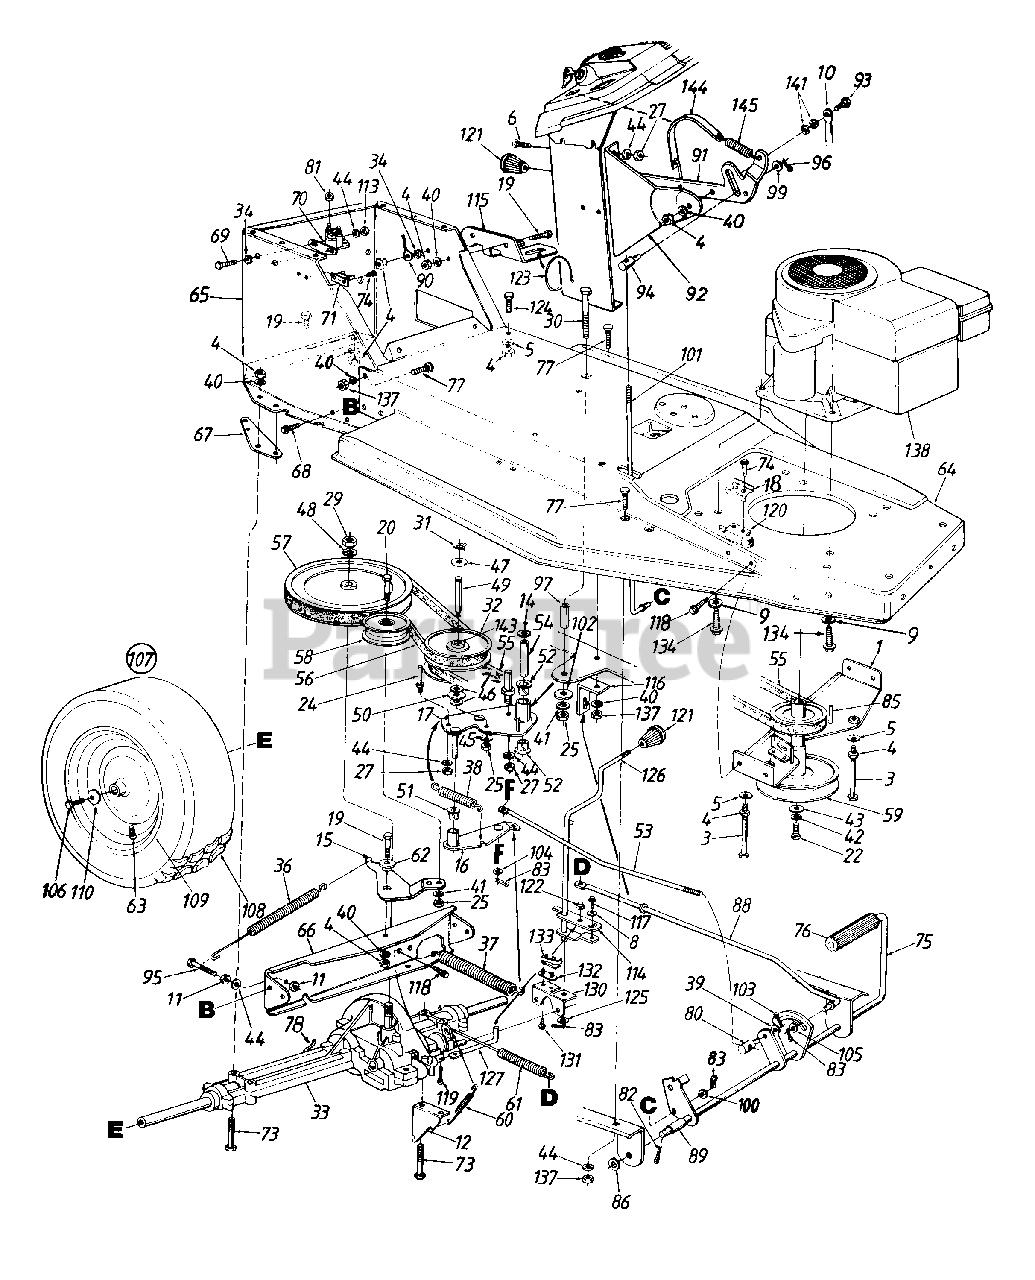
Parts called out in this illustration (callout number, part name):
1	Engine Pulley Belt Guard Ass'y.
3	Hex Bolt 5/16-18 x 5-1/2" Lg.
4	Hex Nut 5/16-18 Thd.
5	Bell-Wash. .345" I.D. x .88
6	Truss-Mach. Scr. 1/4-20 x .50"
7	Belt Guard Pin 1/4-20 Thd.
8	Bell-Wash. .265" I.D. x .75
9	Fl-Wash. 3/8" I.D. x .97" O.D.
10	Speed Selector Brace
11	Hex Nut 1/4-28 Thd.
14	Fl-Wash. 3/8" I.D. x 1.26" O.D.
17	Variable Speed Brkt. Ass'y.
18	Switch Plate
19	Hex Bolt 5/16-18 x .75" Lg.
20	Hex Bolt 3/8-24 x 2.0" Lg. Gr. 5
22	Hex Bolt 7/16-20 x 1.5" Lg.
24	Belt Guard Pin
25	Hex Nut 3/8-24 Thd.
27	Hex Nut 1/4-20 Thd.
29	Hex Jam Nut 9/16-18 Thd.
30	Hex Bolt 3/8-24 x 3.75" Lg.
31	Snap Ring
32	Variable Speed Pulley Ass'y.
33	Transaxle Ass'y. Comp.
34	Ext. L-Wash. 5/16" I.D.
36	Extension Spring 6.12" Lg.
37	Extension Spring 6.74" Lg.
38	Extension Spring 2.59" Lg.
39	Fl-Wash. .385" I.D. x .620"
40	L-Wash. 5/16" I.D.
41	L-Wash. 3/8" I.D.
42	L-Wash. 7/16" I.D.
43	Fl-Wash. .450" I.D. x 1.25"
44	L-Wash. 1/4" I.D.
45	Bell-Wash. .39" I.D. x 1.13"
46	Fl-Wash. .56" I.D. x 1.0" O.D.
47	Washer "Teflon" .565 I.D.
48	Bell-Wash. 9/16" I.D. x 1.125" O.D.
49	Shaft .56" Dia. x 3.875" Lg.
50	Thrust Brg. 1.25 O.D.
51	Flanged Nyliner Brg.
52	Nyliner Flanged Brg.
53	Speed Control Rod
54	Spacer
55	V-Belt
56	V-Belt
57	V-Pulley 8" Dia.
58	Idler Pulley 3-1/8" Dia.
59	Dbl. Pulley 6.0" Dia. x 3.56"
60	Extension Spring 3.18" Lg.
61	Extension Spring 7.08" Lg.
62	Shld. Spacer .500" Dia.
63	Air Valve
69	Hex Bolt 1/4-20 x .62" Lg.
70	Solenoid
71	Circuit Breaker
73	Hex Bolt 5/16-18 x 2.75" Lg.
74	Truss Mach. B-Tap Scr. #10 x .50" Lg.
75	Foot Pedal Rod Ass'y. (Style 0 & 2)
77	Ribbed Neck Bolt 5/16-24 x .84"
78	Spring Anchor
80	Ferrule
81	Hex Sems Nut 1/4-20 Thd.
82	Cot-Pin 1/8" Dia. x 1.25" Lg.
83	Cot-Pin 3/32" Dia. x .75" Lg.
85	Sq. Key 1/4 x 2.0" Lg.
86	Fl-Wash. .635" I.D. x 1.0"
88	Brake Rod
89	Spacer 5/8" I.D. x 1.2" Lg.
90	Ground Wire 7.25" Lg.
91	Speed Selector Lever
92	5 Speed Selector Brkt.
92	7 Speed Selector Brkt.
93	Shld. Bolt .437" Dia. x .47" Lg.
94	Ferrule
95	Hex Bolt 1/4-28 x 1.25" Lg.
96	Intern. Cot-Pin 5/16" Dia.
97	Spacer .375" I.D. x .625"
99	Fl-Wash. .344" I.D. x .62"
100	Fl-Wash. .25" I.D. x .62" O.D.
101	Speed Control Rod
102	Fl-Wash. 3/8" I.D. x 1.25" O.D.
103	Cot-Pin 1/8" Dia. x 1.0" Lg.
104	Fl-Wash. .34" I.D. x .68"
105	Fl-Wash. .34" I.D.
106	Hex L-Bolt 5/16-24 x .75" Lg.
110	Bell-Wash. .345" I.D. x .88"
113	Hex Jam Nut 1/4-20 Thd.
114	Shift Lever Adjusting Link
115	Shift Lever Spring Brkt.
118	Hex Wash. Hd. Tap Scr. 1/4-20 x .5" Lg.
119	Intern. Cotter Pin
120	Safety Switch (Clutch)
121	Knob
122	Retaining Ring
123	Compression Spring 1.5" Lg.
124	Hex Wash. Hd. Scr. 5/16-18 x 7/8" Lg.
125	Fl-Wash. .469" I.D. x .88"
130	Shift Lever Support
131	Hex Wash. Hd. #8 x .50" Lg.
132	Insulator Nut Plate
133	Spring Switch
134	Hex Tap Scr. 3/8-16 x 1.25"
137	Hex Nut 5/16-24 Thd.
138	Engine
141	Wave Wash. .445" I.D.
143	Needle Brg.
144	7-Speed Indicator Strip
145	Ext. Spring 2.04" Lg.
